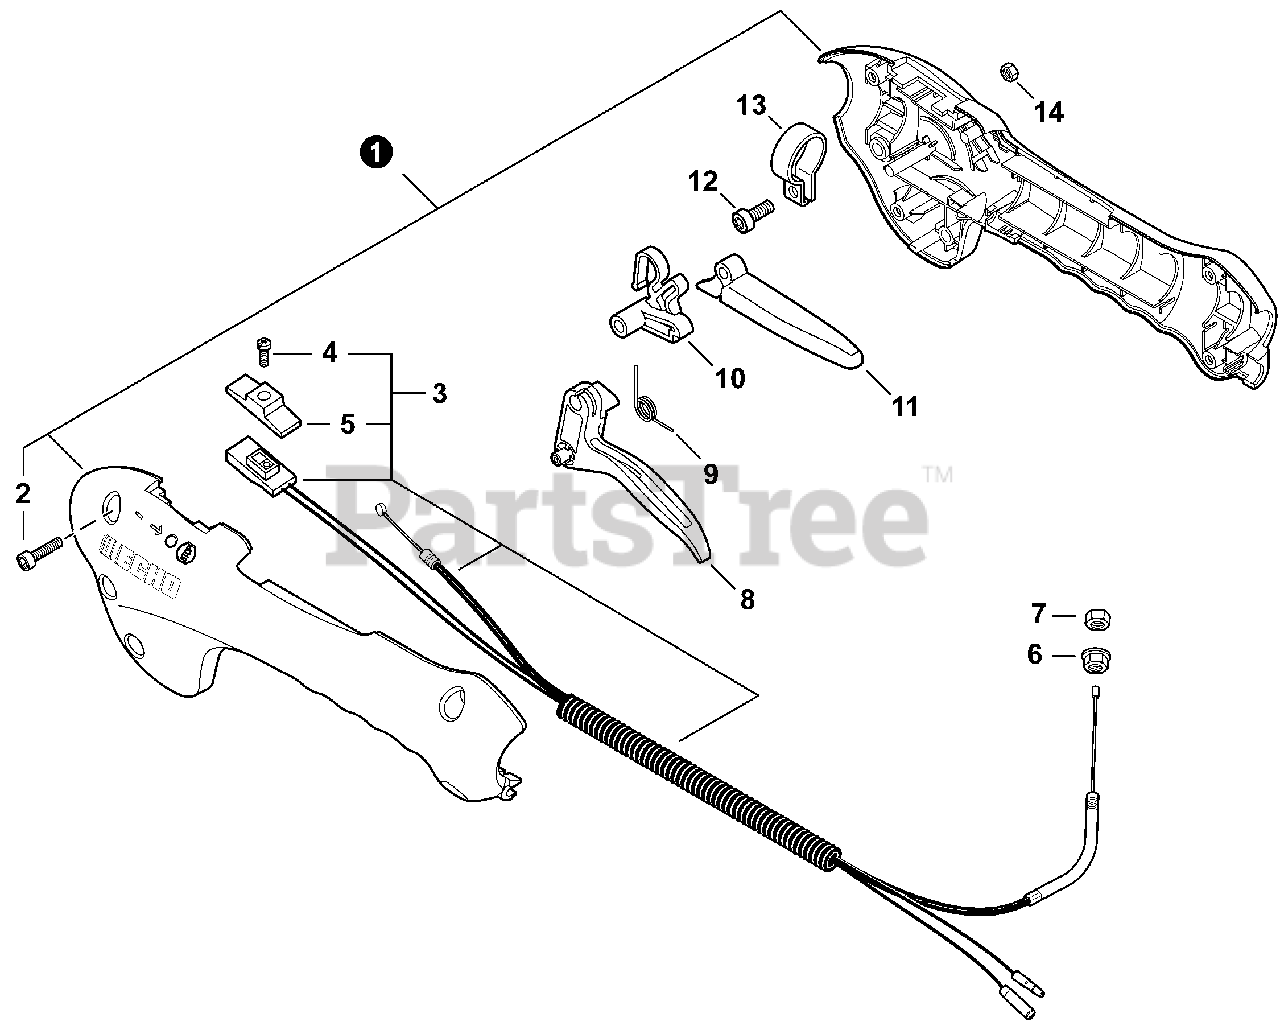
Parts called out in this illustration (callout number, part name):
1	CONTROL HANDLE SET
2	BOLT, TORX 4×16
3	CABLE ASSY, CONTROL
4	SCREW 3×10
5	KNOB, SWITCH - ORANGE
6	NUT, FLANGE M6
8	TRIGGER, THROTTLE
9	SPRING, TRIGGER
10	LOCKOUT, THROTTLE
11	LEVER, THROTTLE LOCKOUT
12	BOLT, TORX 5×16
14	NUT - 5
